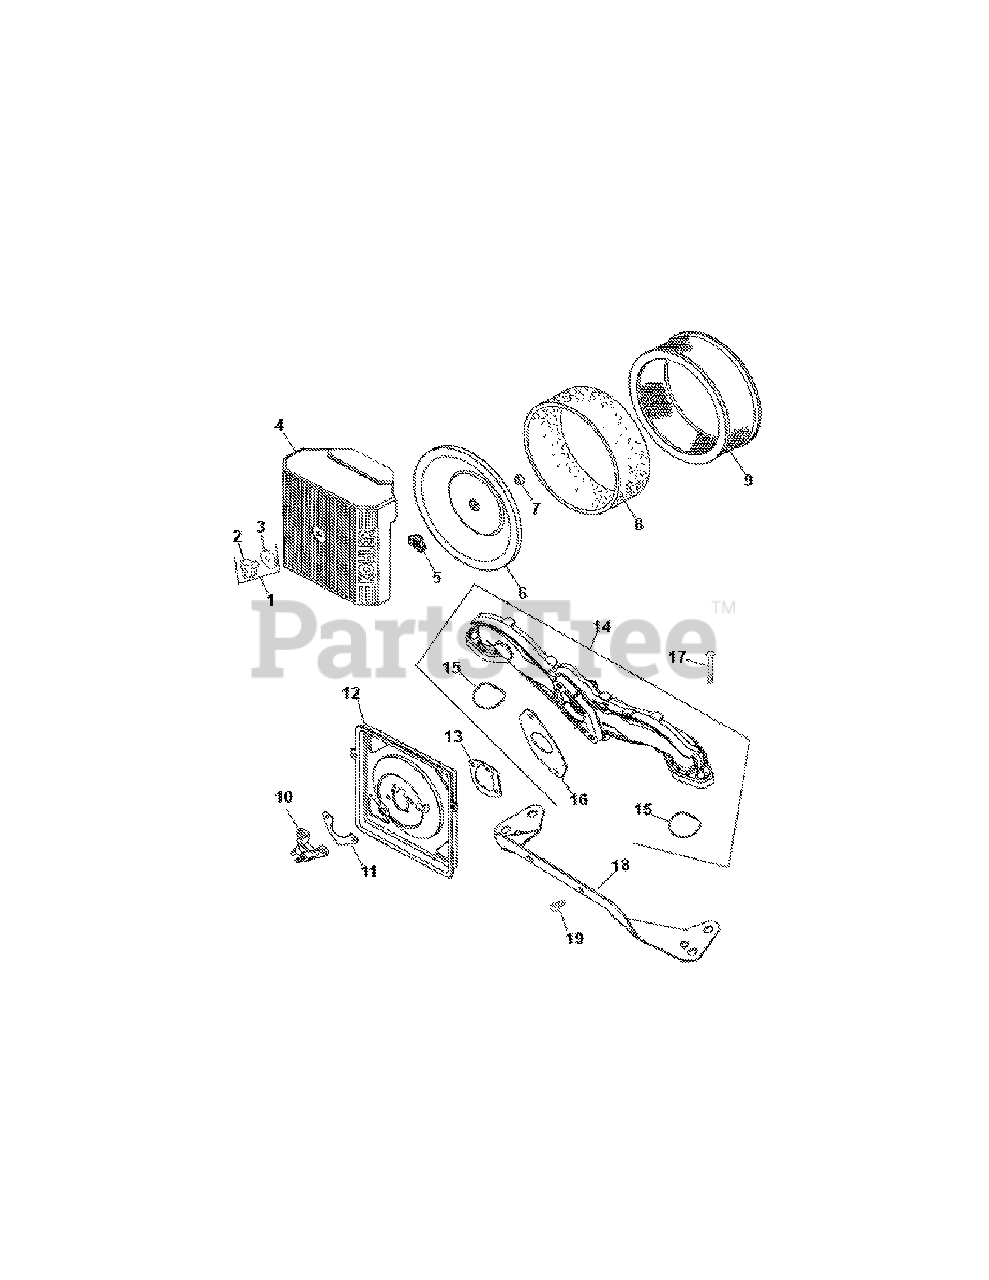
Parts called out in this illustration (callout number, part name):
1	Knob With Seal Kit
4	Air Cleaner Cover
6	Inner Air Cleaner Cover
7	Inner Air Cleaner Seal
8	Precleaner Element
9	Air Cleaner Element
10	Spit Back Cup w/Stud
11	Spit Back Cup Gasket
12	Air Cleaner Base
13	Air Cleaner Gasket
14	Intake Manifold
15	Intake Port O-Ring
16	Carburetor Gasket
17	Hex Flange Screw (M6 x 1.0 x 40)
18	Air Cleaner Bracket
19	Hex Flange Screw (M5 x .8 x 10)
